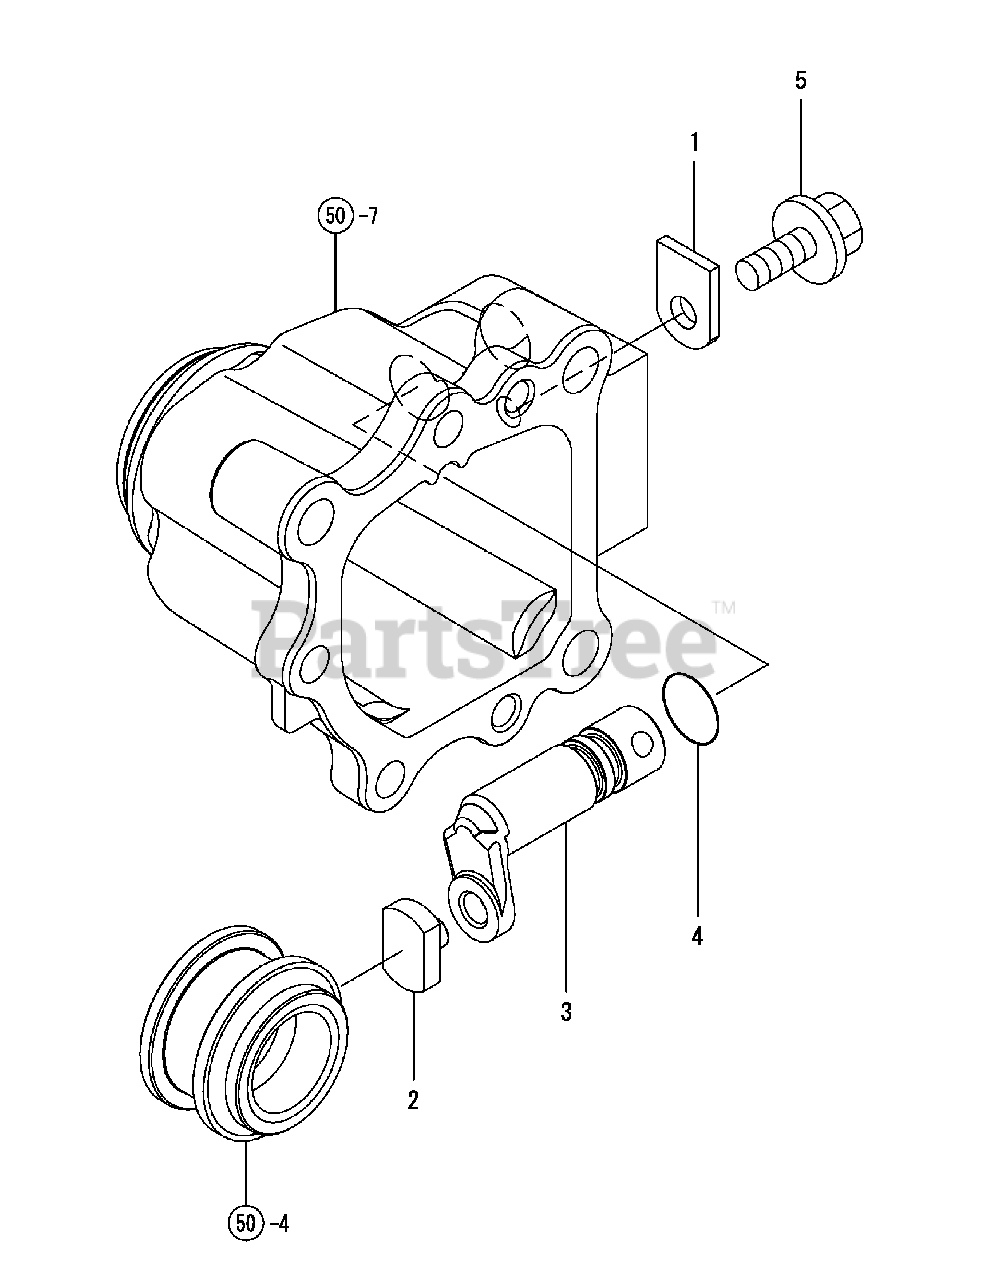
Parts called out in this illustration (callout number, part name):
2	BLOCK, SHIFT FRONT
3	SHIFT, SHAFT 4WD
4	O-RING 1A P-12.5
5	BOLT M 8X 16 PLATED
